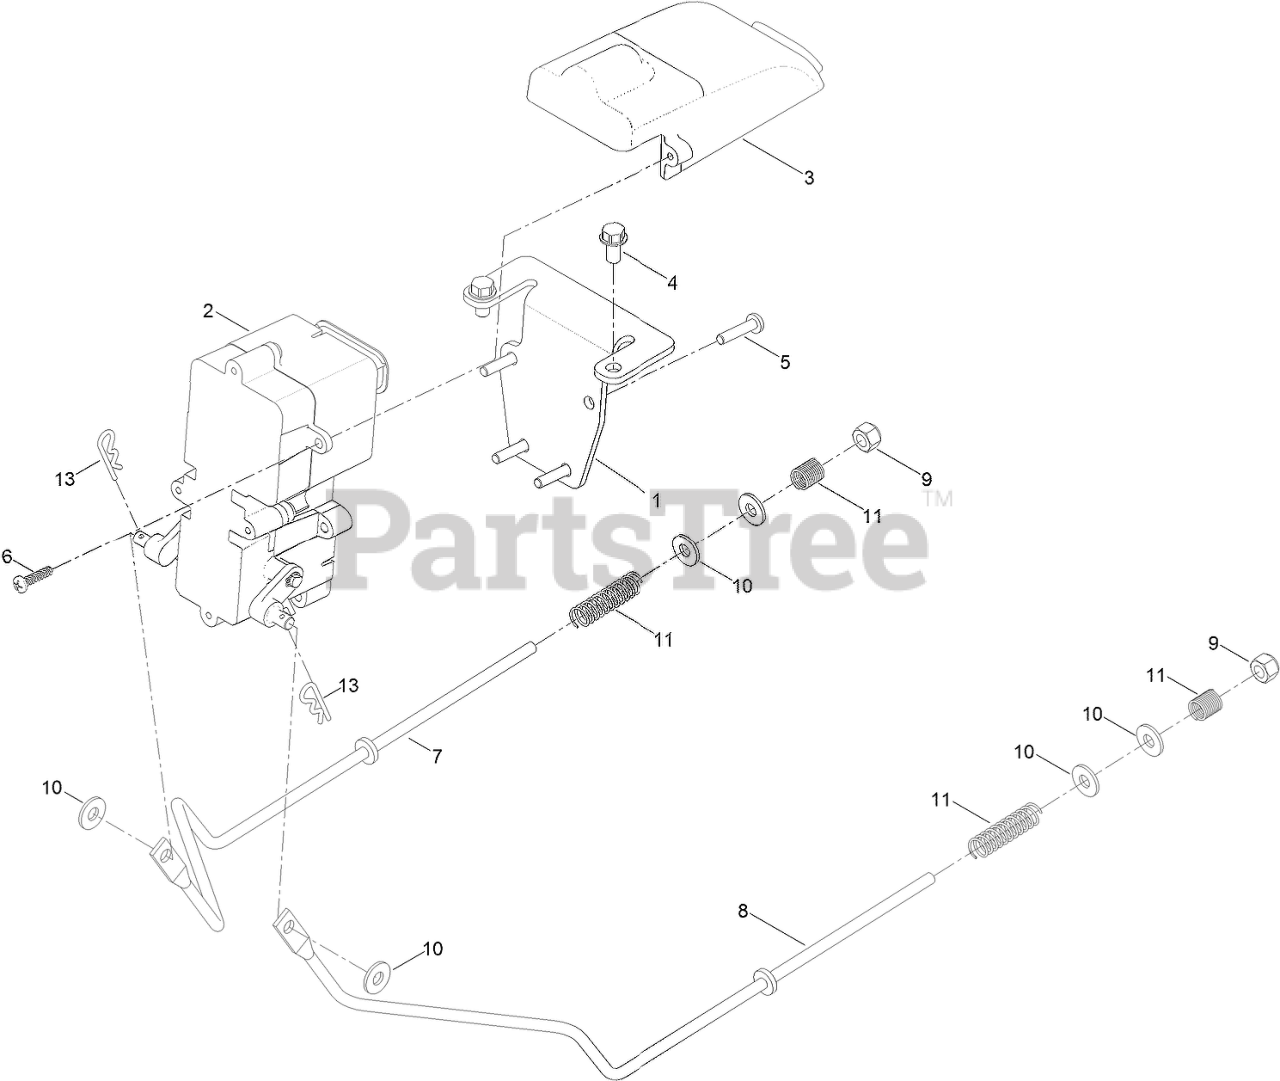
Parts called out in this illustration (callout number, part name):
1	BRACKET-MOUNT, BRAKE
2	BRAKE BOX ASM
3	COVER-CONNECTOR
4	SCREW-HWH
5	SCREW-PPH
6	SCREW-PPH
7	ROD-BRAKE, WIDE (RH)
8	ROD-BRAKE, WIDE (LH)
9	NUT-LOCK, NI
10	WASHER
11	SPRING-COMPRESSION
13	PIN-COTTER
